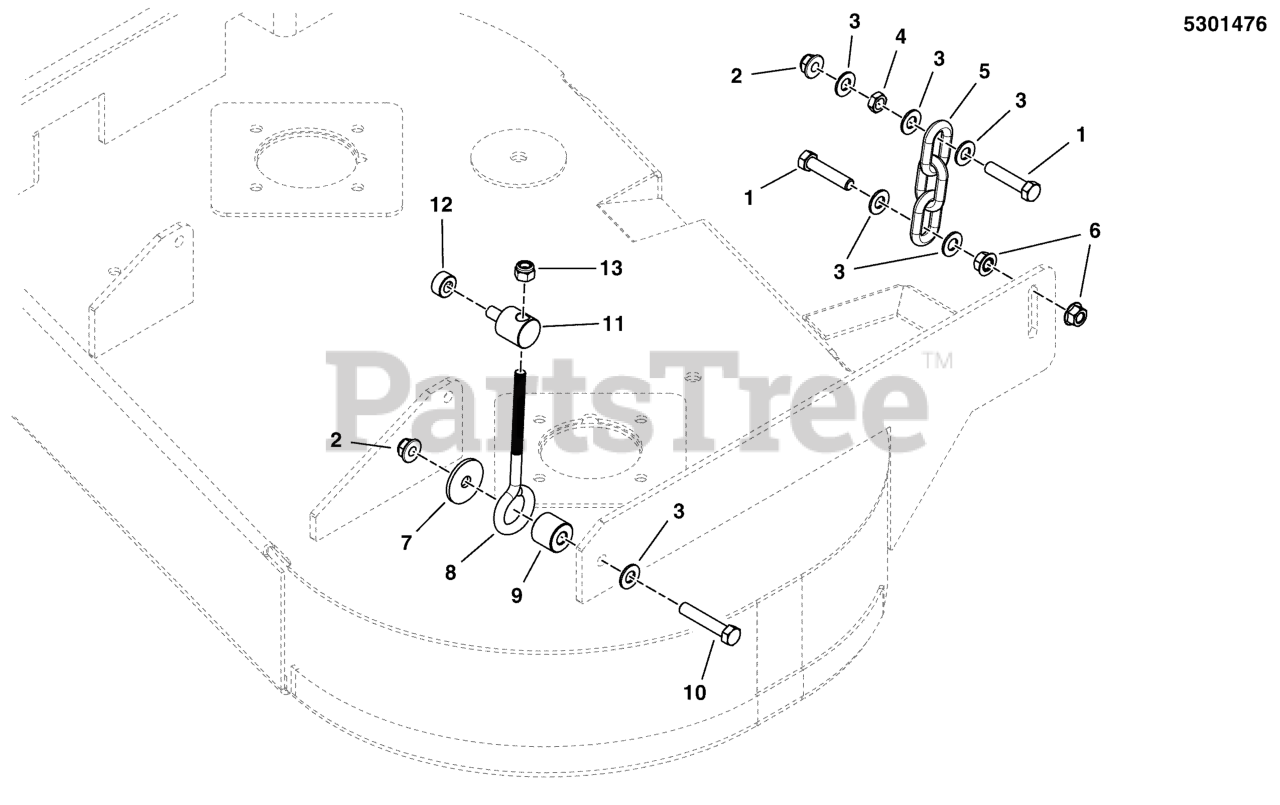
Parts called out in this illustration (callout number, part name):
1	BOLT, 3/8-16 X 1-3/4" GD5 CZ
2	NUT, 3/8-16 HEX NYLOCK FLANGE
3	WASHER, 3/8 SAE
4	NUT, 3/8-16 HEX JAM
5	CHAIN, 5/16 GD30, 3 LINKS
6	NUT, 3/8-16 HEX SERRATED FLANGE
7	WASHER, .390 X 1.50 X .109, YZ
8	EYE BOLT, 3/8-16X6,3THRD,1EYE,CZ, WELDED
9	SPACER-0.390ID 0.90 OD 0.70LG P'MTL
10	BOLT, 3/8-16 X 2, GD5, CZ
11	ADJUSTER, BRAKE LINKAGE
12	COLLAR, 3/8 SET
13	NUT, 3/8-16 HEX NYLON LOCK
